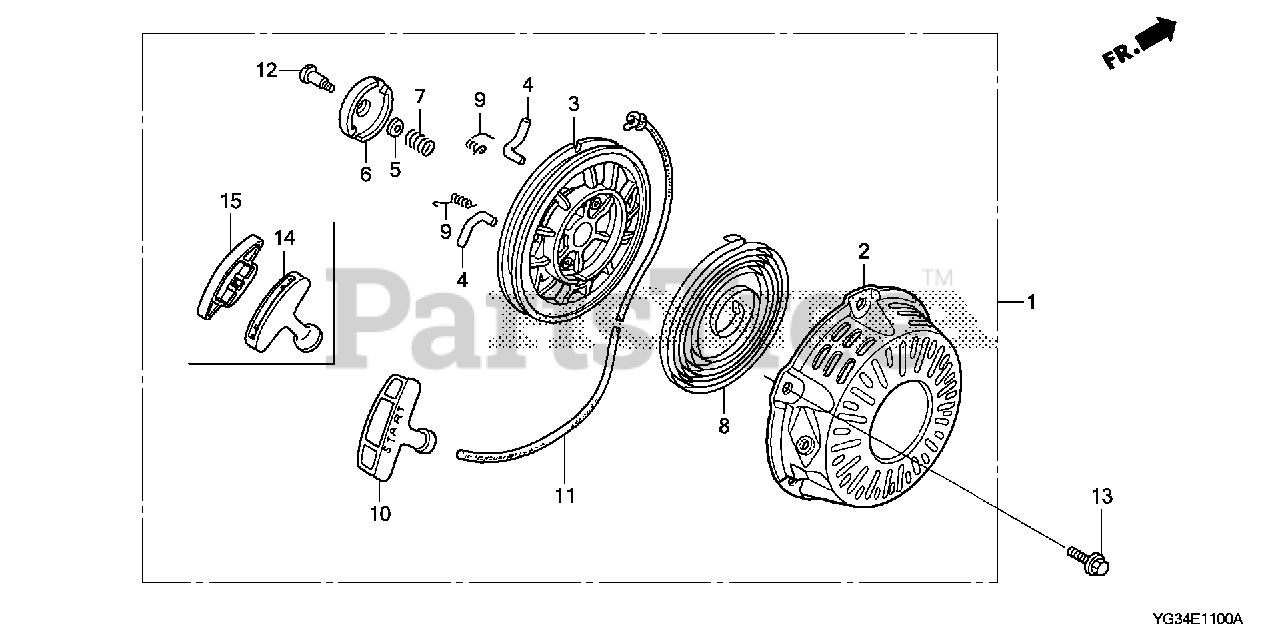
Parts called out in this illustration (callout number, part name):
1	STARTER ASSY., RECOIL *R280* (COO)(FOR U.S.A.) (POWER RED)
2	CASE, RECOIL STARTER *R280* (POWER RED)
3	REEL, RECOIL STARTER
4	RATCHET, STARTER
5	PLATE, FRICTION
6	GUIDE, RATCHET
7	SPRING, FRICTION
8	SPRING, RECOIL STARTER
9	SPRING, RETURN
11	ROPE, RECOIL STARTER
12	SCREW, SETTING
13	BOLT, FLANGE (6X10)
13	BOLT, FLANGE (6X8)
14	KNOB, RECOIL STARTER (COO)(FOR U.S.A.)
15	KNOB, REINFORCEMENT
